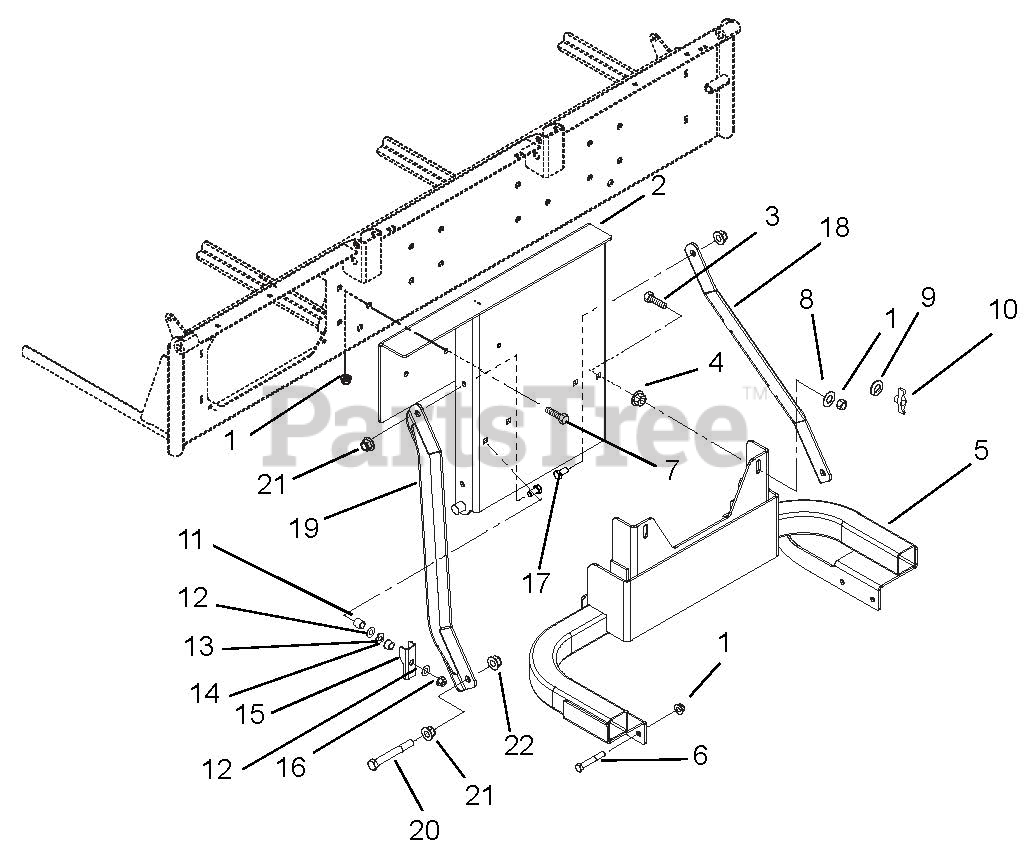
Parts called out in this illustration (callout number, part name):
1	Nut, .38-16 Nyloc Flange
2	Upper Mount, 3-Bag
3	Bolt, Round Head Square Neck .38-16 x 1.75 Grade 5
4	Nut, Spinlock Flange .375
5	Mount, Rear Bagger
6	Bolt, Hex .38-16 x 2.50 Grade 5
7	Bolt, Hex .38-16 x 1.00 Grade 5
8	Washer, Flat Steel .406 x 1.50 x .245
9	Washer, Locking .375 x .115 Heavy
10	Nut, Wing .38-16
11	Spacer .41 x .75 x .88
12	Washer, Flat Steel .438 x 1.00 x .083
13	Wave Washer .640 x .875 x .125 Free Height
14	Bushing, Sleeve .377 x .624 x .235
15	Latch, Bagger Upper Mount
16	Nut, Locking Top Flange .38-16
17	Bolt, .50-13 x 1.00 Hex
18	Weldment, Support, Bagger, LH
19	Weldment, Support, Bagger, RH
20	Hex Bolt .50-13 x 4.00
21	Locking Nut .50-13
22	Flange Nut .50-13
